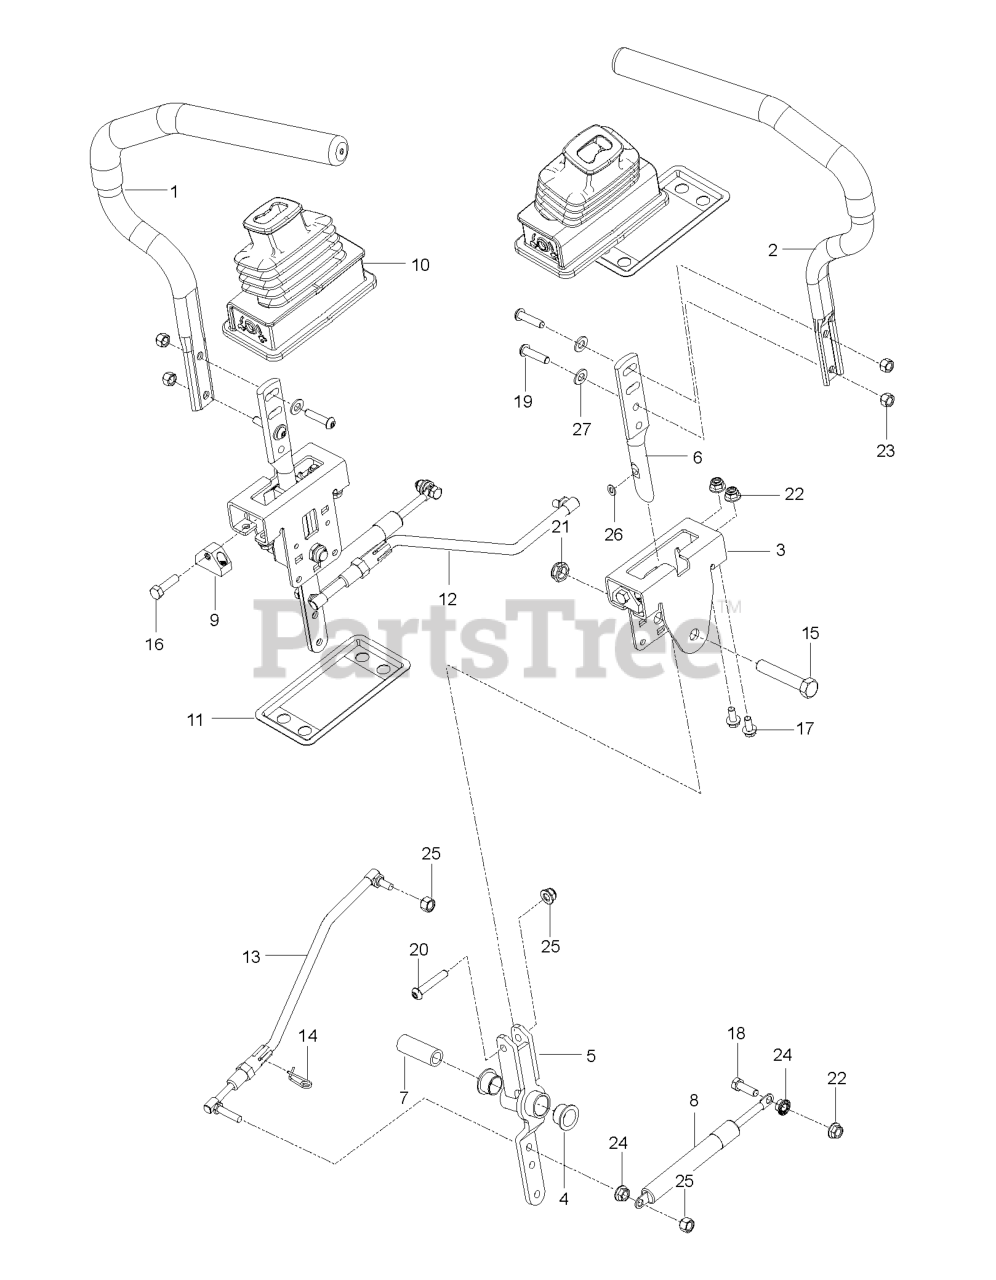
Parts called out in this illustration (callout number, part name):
1	TUBE.LEVER.CNTL.ASM.ZTR.RT.SVC
2	TUBE.LEVER.CNTL.ASM.ZTR.LT.SVC
3	BRACKET.CONTROLS.ZTR.X431
4	BEARING, FLANGE
5	LEVER CONTROL PIVOT
6	CONTROL.LEVER.HANDLE
7	SPACER.PIVOT.CONTROL
9	BLOCK TRACKING CONTROL ZTR
10	BOOT.STEERING.LEVER
11	CONTROL.BOOT.FLANGE.X431
12	ROD.ASM.RH.ADJUSTABLE
13	ROD.ASM.LH.ADJUSTABLE
14	RETAINER.CLIP.SPRING.S
15	HCS 1/2-13 X 2-3/4 GD 5 ZD
16	SCREW.SHAKEPROOF.1.25.BLACK
17	HHFS 5/16-18 X 3/4
18	BOLT.FIN.HEX.5/16-18UNC X 1.00
19	BUTTONHEAD.5/16-18X1.125.BLACK
20	SCREW 5/16-18 X 1 3/4 BTN-HD
21	NUT 1/2-13 HEX JM NYL
22	5/16-18 NYLOC FLANGE NUT
23	NYLOCK.NUT.5/16-18 BLACK
24	NUT 5/16C WHIZ
25	NUT.71038.31-18.HEX.NYLOCK
26	WASHER.11/32ID.11/16OD.116THIC
27	WASHER.11/32X11/16 BLACK
